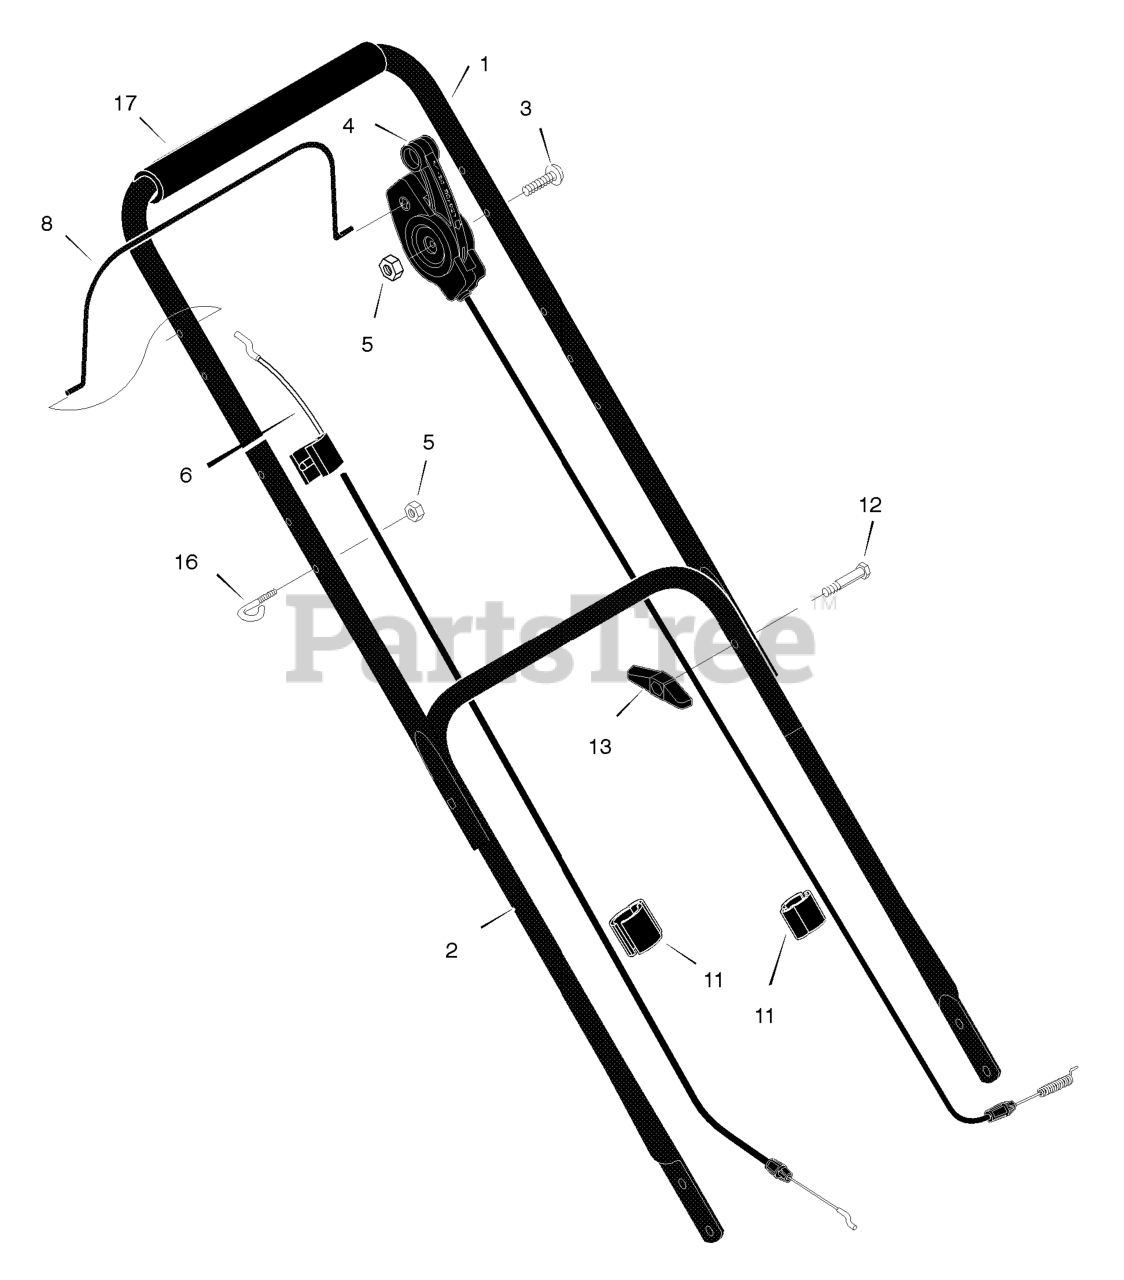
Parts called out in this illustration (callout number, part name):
1	Handle, Upper (Black)
2	Handle, Lower (Black)
4	Control, Drive
5	Locknut
6	Cable, Stop
8	Lever, Stop
11	Fastener, Cable
13	Knob
16	Guide, Rope
17	Tubing, Foam
